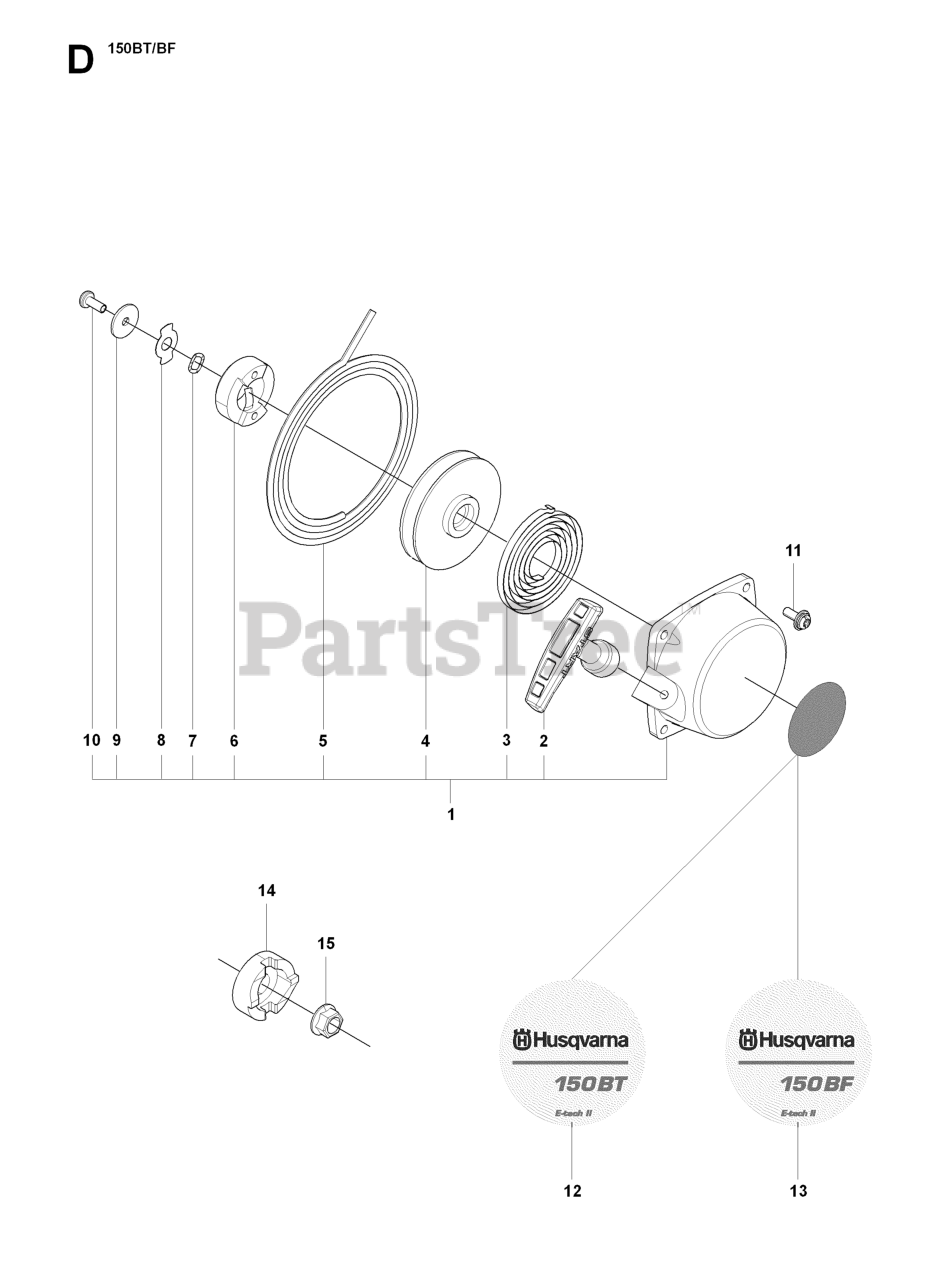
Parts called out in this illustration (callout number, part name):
1	STARTER ASSY
4	STARTER PULLEY
5	STARTER ROPE
6	STARTER PAWL
8	RETAINER
9	WASHER
13	STARTER PAWL
14	NUT
